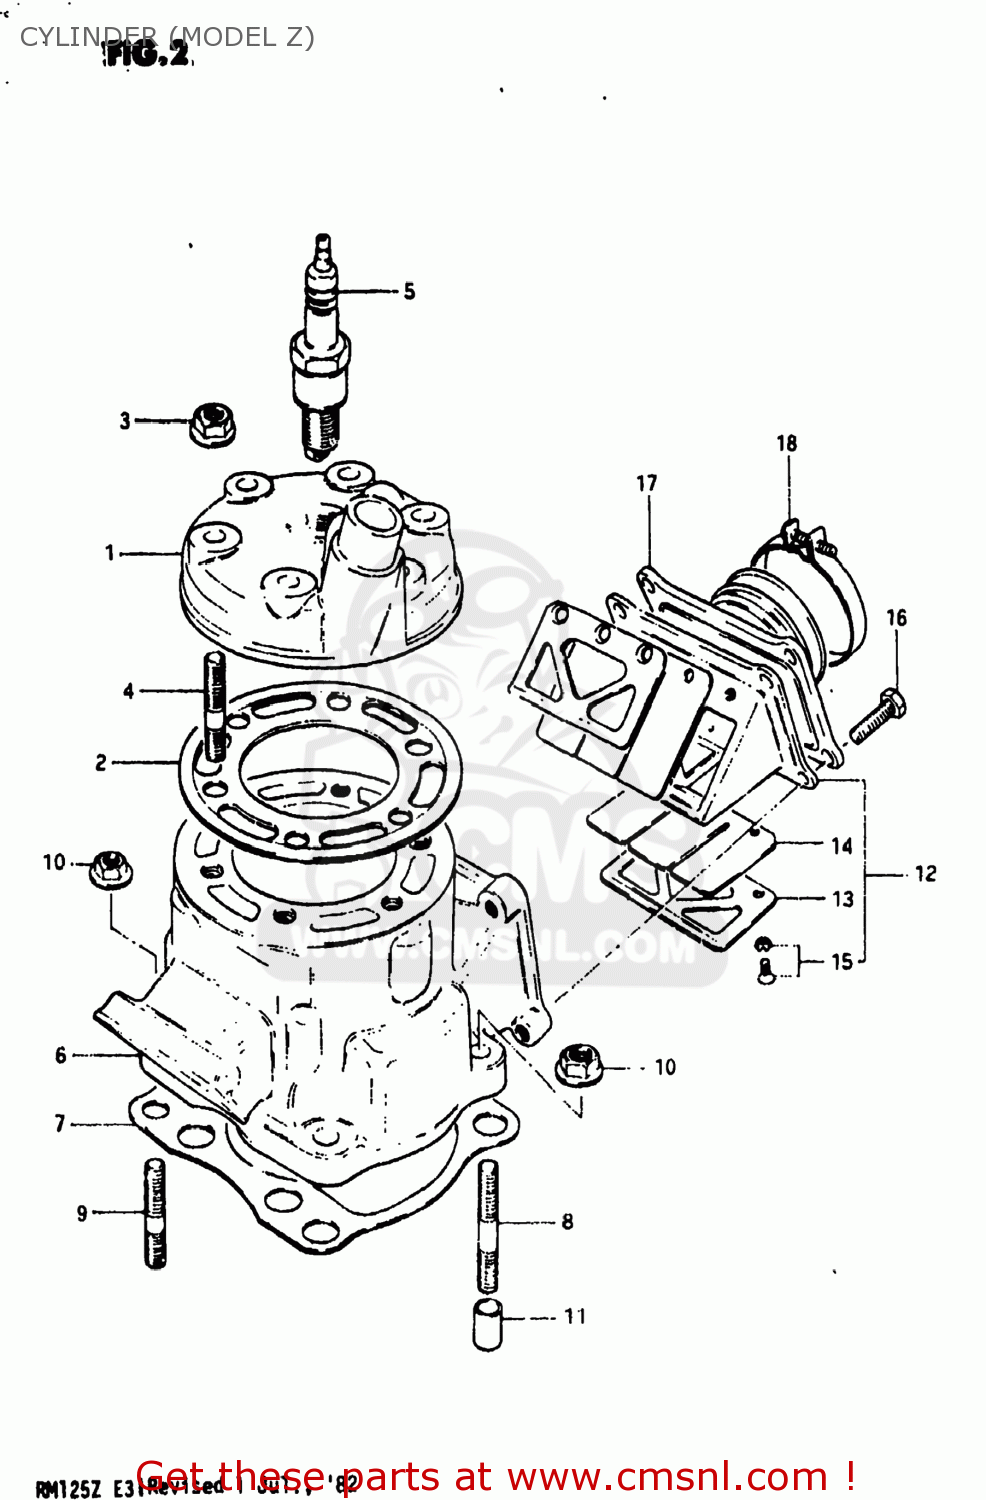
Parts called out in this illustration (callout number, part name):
1	HEAD,CYLINDER.
2	GASKET,CYLINDER HEAD (MCA)
3	NUT 8MM
4	STUD
5	SPARK PLUG
6	CYLINDER
7	GASKET,CYLINDER (MCA)
8	STUD
9	STUD
10	NUT 8MM
11	PIN
12	VALVE ASSEMBLY,REED
13	STOPPER,REED VALVE
14	VALVE,REED
15	SCREW
16	BOLT
17	PIPE,INTAKE
18	CLAMP
